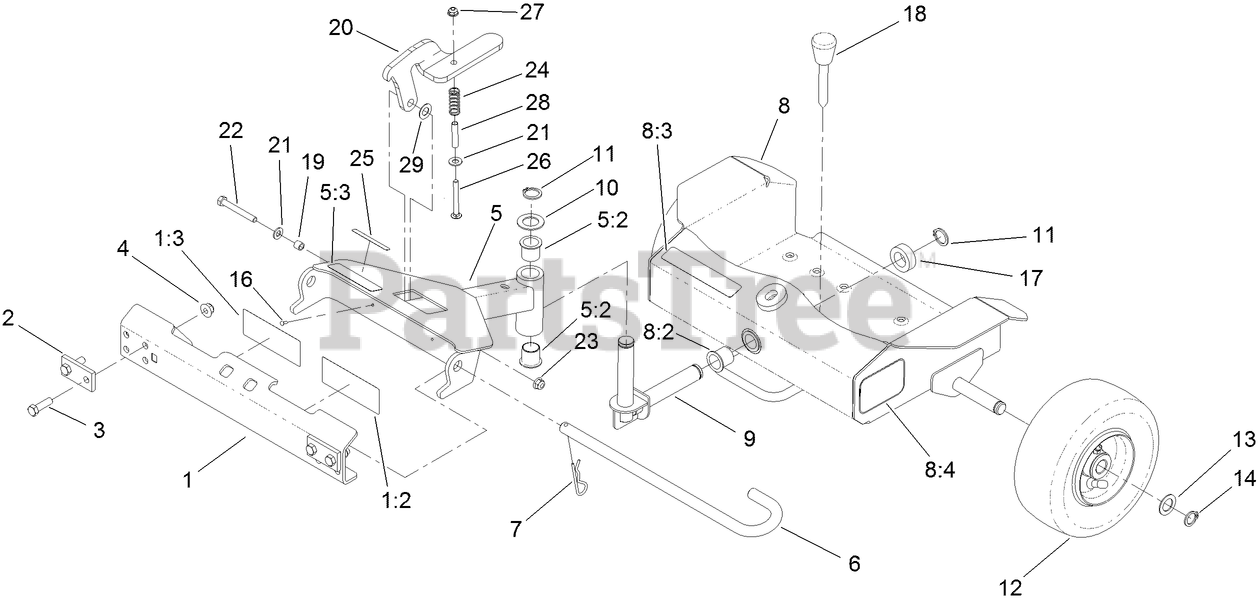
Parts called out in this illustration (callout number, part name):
1	ASM, MOUNT PLATE W/ DECALS
1:2	DECAL-BELT DRIVE WARNING
1:3	DECAL-WARNING, SULKY
2	PLATE,BACK-UP (PLATED)
3	SCREW-HH
4	NUT-HF, NI
5	ASM, SULKY DRAWBAR W/ DECALS
5:2	BUSHING, IGUS
5:3	DECAL-SULKY DANGER
6	PIN, PIVOT
7	PIN-COTTER
8	ASM, SULKY PLATFORM W/ DECALS
8:2	BUSHING, IGUS
8:3	DECAL-SULKY HAZARD
8:4	DECAL
9	SULKY PIVOT WELDMENT
10	WASHER-FLAT
11	RING-RETAINING, EXT
12	WHEEL ASM
13	WASHER-THRUST
14	RING-RETAINING
16	RIVET
17	SPACER-CASTER
18	PIN-HOC
19	SPACER
20	LATCH-TRANSPORT, SULKY
21	WASHER-PLAIN
22	SCREW-HH
23	NUT-HF, NI
24	SPRING-COMPRESSION
25	DECAL-WARNING
26	SCREW-CARR
27	NUT-HF
28	SPACER-THROTTLE
29	WASHER-SPECIAL
